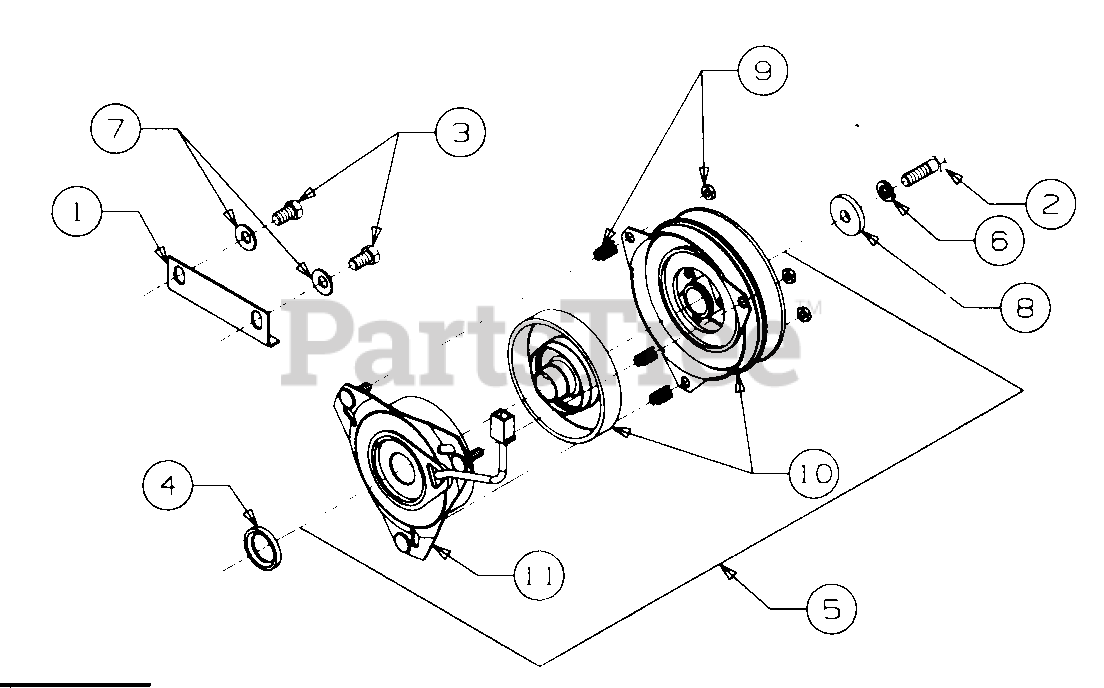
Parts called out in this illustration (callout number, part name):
3	Screw, Hex Cap, 7/16-14 x .75 Lg GR5
4	Spacer, 1.13 ID x 1.62 OD x .47 Thk
5	Clutch Assy, PTO
6	Washer, Lock, 7/16
7	Washer, Bell, .45 x 1.0 x .062 Thk
8	Washer, Flat, .47 x 1.5 x .225 Thk
9	Mounting Accessories
10	Kit, Armature and Rotor
11	Field Assy
